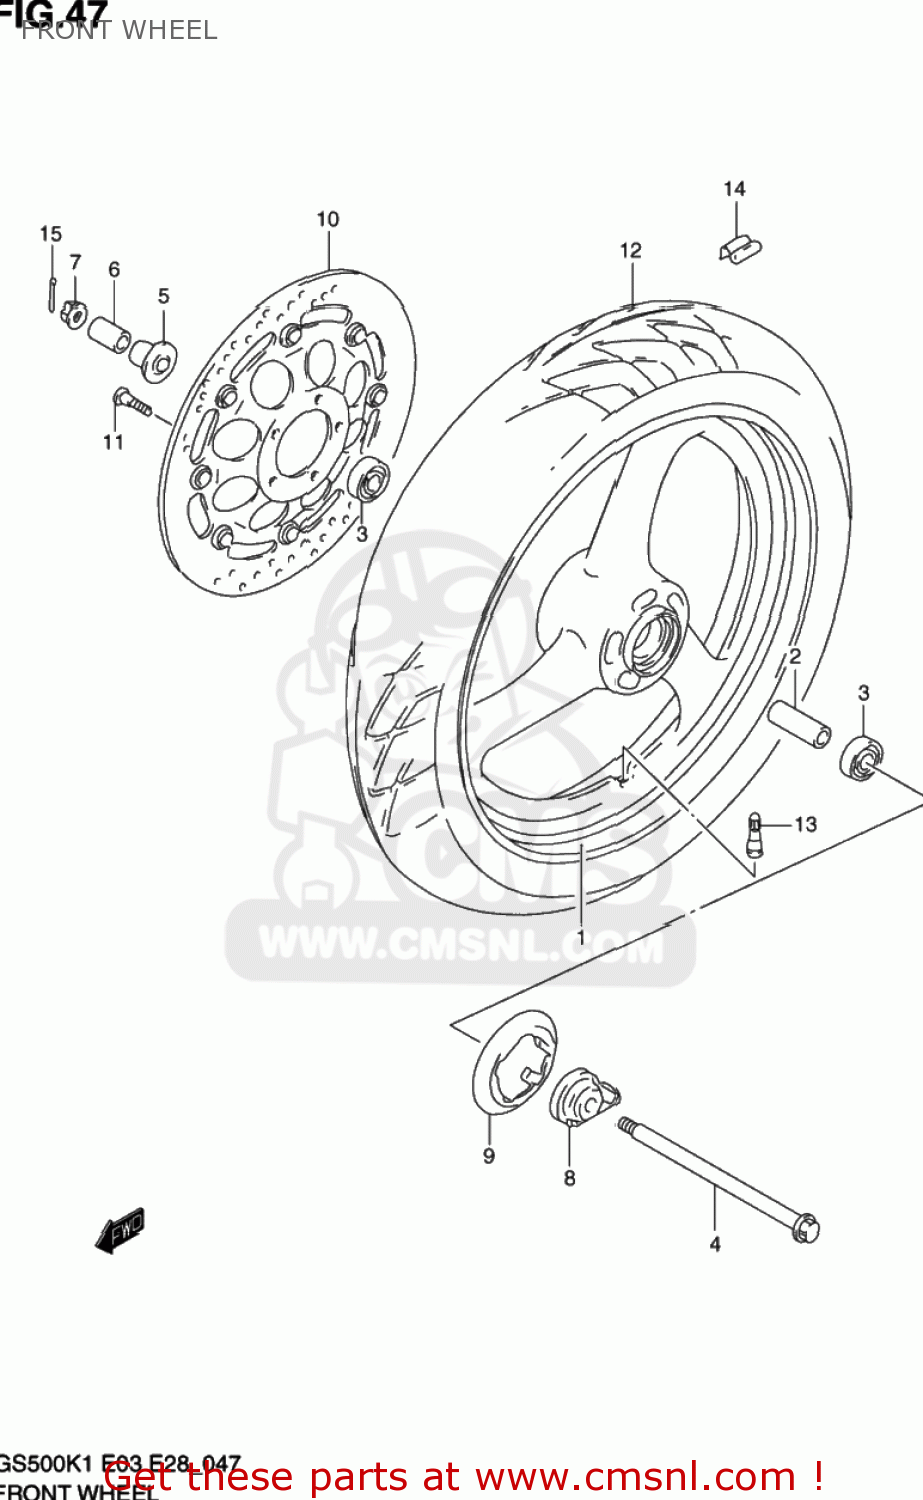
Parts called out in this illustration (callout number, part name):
1	FR WHEEL
2	SPACER(15.3X21.7X63)
3	BEARING
4	AXLE,FR
5	SPACER,FR AXLE
6	SPACER,FR AXLE,R
7	NUT
8	BOX ASSY,SPEEDOMETER GEAR
9	COVER,FR HUB,R
10	DISC,FR BRAKE,R
11	BOLT 8X33
12	TIRE,T/L(110/70-17 54H)
13	VALVE ASSY,WHEEL RIM(TR412)
14	BALANCER,WHEEL (10G)
15	COTTER PIN
